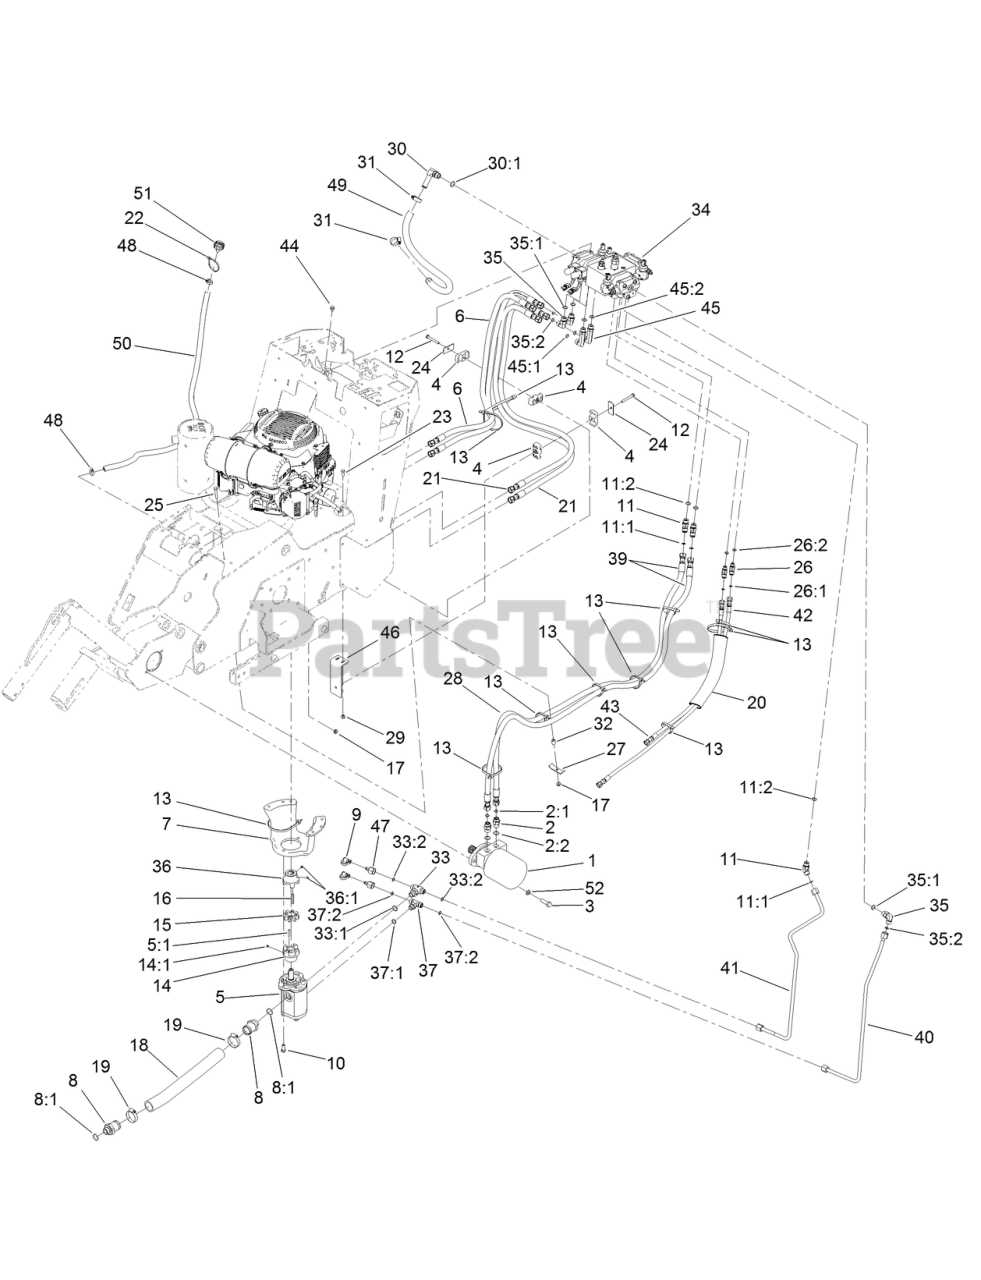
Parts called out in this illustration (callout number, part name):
1	HYDRAULIC MOTOR ASM
2	FITTING-STRAIGHT
2:1	O-RING
2:2	O-RING
3	SCREW-HH
4	CLAMP-TUBE
5	PUMP-HYD
5:1	KEY-SQUARE
6	HYDRAULIC HOSE ASM
7	MOUNT-PUMP
8	FITTING-STR
8:1	O-RING
9	CAP-DUST
10	SCREW-HH
11	FITTING-HYD, 45 DEG
11:1	O-RING
11:2	O-RING
12	SCREW-HH
13	TIE-CABLE
14	COUPLER-FLEX
14:1	SCREW-SET, HSH
15	COUPLER-SPIDER
16	KEY-SQUARE
17	NUT-HF
18	HOSE-SUCTION, HYD
19	CLAMP-HOSE
20	SLEEVE-PROTECTIVE
21	HYDRAULIC HOSE ASM
22	TIE-CABLE
23	SCREW-HH
24	PLATE-COVER
25	SCREW-HH
26	FITTING-ELBOW, 45 DEG
26:1	O-RING
26:2	O-RING
27	BRACKET-CLAMP
28	SLEEVE-PROTECTIVE
29	NUT-HF, NI
30	FITTING-90
30:1	O-RING
31	CLAMP-HOSE
32	SPACER
33	FITTING-HYD
33:1	O-RING
33:2	O-RING
34	VALVE ASM
35	FITTING-ELBOW, 90 DEG
35:1	O-RING
35:2	O-RING
36	HUB-FLEX (1.125" SHAFT)
36:1	SCREW-SET, HSH
37	FITTING-HYD, TEE
37:1	O-RING
37:2	O-RING
39	HYDRAULIC HOSE ASM
40	HYD TUBE ASM
41	HYD TUBE ASM
42	HYDRAULIC HOSE ASM
43	HOSE-HYD
44	SCREW-HHF
45	FITTING-ELBOW 90 LONG
45:1	O-RING
45:2	O-RING
46	BRACKET-SUPPORT, HOSE
47	FITTING
48	CLAMP-HOSE
49	HOSE-COOLER
50	HOSE-BREATHER
51	BREATHER
52	WASHER-LOCK
